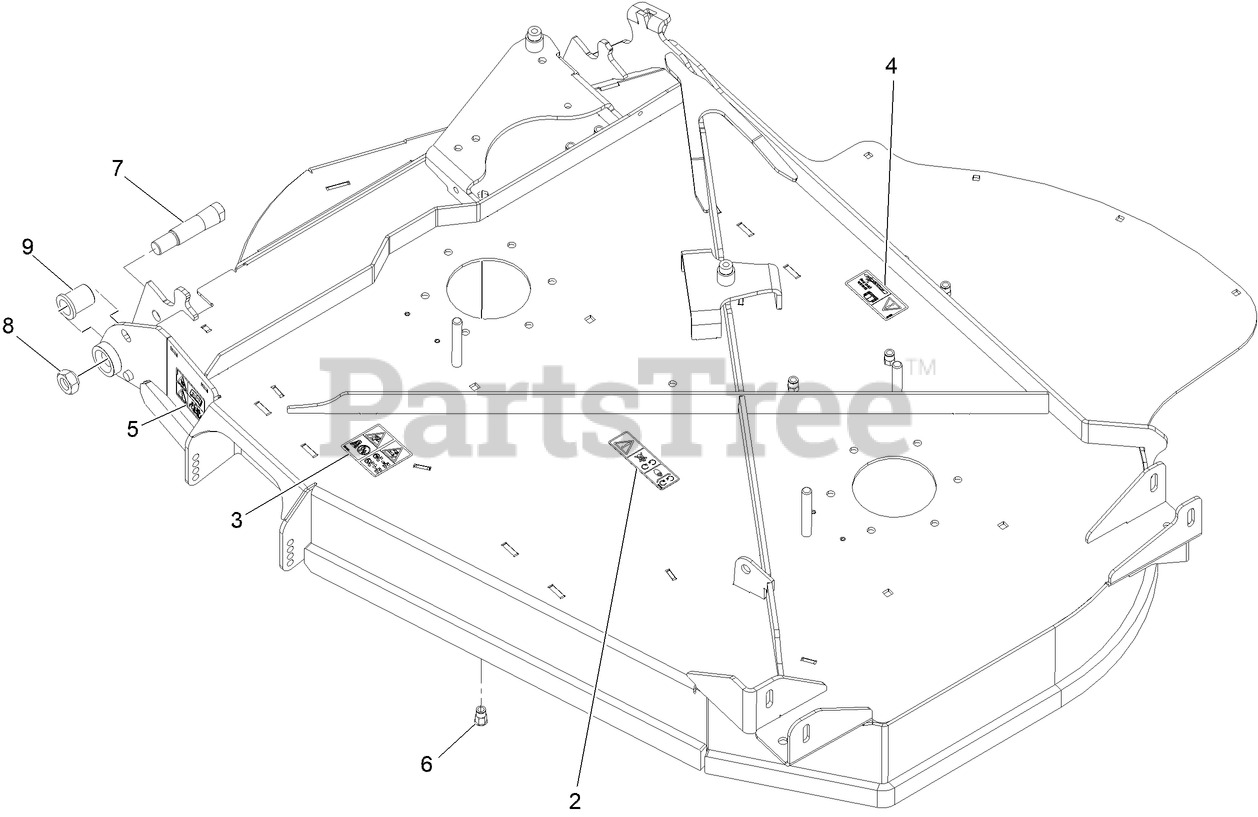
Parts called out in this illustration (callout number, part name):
2	DECAL-COVER, MISSING
3	DECAL-DANGER, THROWN OBJECT
4	DECAL-TORQUE, BOLT
5	DECAL-WARNING, PINCH POIN
6	NUT-CLINCH,HEX
7	BOLT-PIVOT PIN
8	NUT-LUG
9	BUSHING-FLANGED
